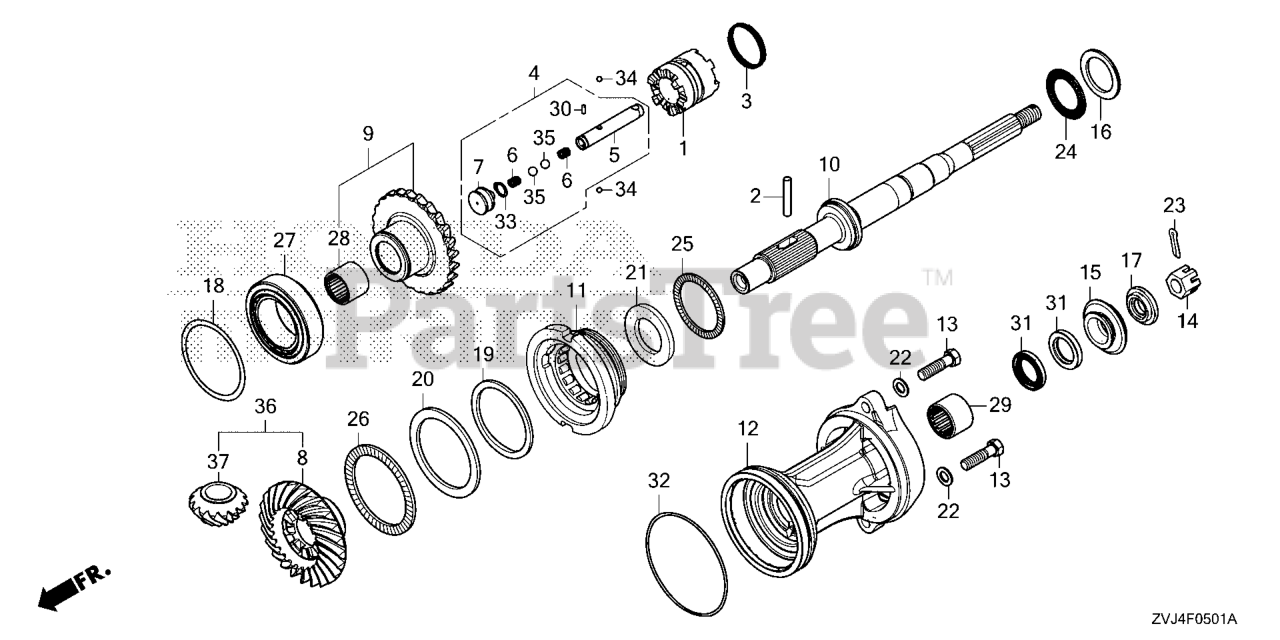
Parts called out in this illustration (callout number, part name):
1	SHIFTER, CLUTCH
2	PIN, SHIFTER (8X50)
3	RING, CROSS PIN
4	SLIDER, SHIFT
5	SLIDER, SHIFT
6	SPRING, SHIFT
7	PLATE, SHIFT
8	GEAR, BEVEL (24T) (FORWARD)(COUNTER ROTATION)
9	GEAR, BEVEL (24T) (REVERSE)(COUNTER ROTATION)
10	SHAFT, PROPELLER
11	HOLDER ASSY., BEARING (COUNTER ROTATION)
12	HOLDER, PROPELLER SHAFT *NH565* (GRAND PRIX WHITE)
12	HOLDER, PROPELLER SHAFT *NHB14M* (AQUA MARINE SILVER METALLIC)
12	HOLDER *NH565*
12	HOLDER *NHB14M*
13	BOLT, HEX. (12X45)
14	NUT, CASTLE (18MM)
15	WASHER, PROPELLER THRUST
16	WASHER, THRUST BEARING
17	WASHER, PROPELLER
18	SHIM A, BEVEL (0.10)
18	SHIM B, BEVEL (0.15)
18	SHIM C, BEVEL (0.30)
18	SHIM D, BEVEL (0.50)
19	SHIM A, BEVEL (0.10) (COUNTER ROTATION)
19	SHIM B, BEVEL (0.15) (COUNTER ROTATION)
19	SHIM C, BEVEL (0.30) (COUNTER ROTATION)
19	SHIM D, BEVEL (0.50) (COUNTER ROTATION)
20	WASHER, THRUST (85X110X2)
21	WASHER, THRUST (48X74X3) (COUNTER ROTATION)
22	WASHER, PLAIN (12MM)
23	PIN, SPLIT (4.0)
24	BEARING, THRUST (F)
25	BEARING, NEEDLE (50X72X4.5)
26	BEARING, THRUST NEEDLE (85X110X4)
27	BEARING, RADIAL BALL (55X100X21)
28	BEARING, NEEDLE (28X39X30)
29	BEARING, NEEDLE (32X42X30)
30	ROLLER (3X13.8)
31	SEAL, WATER (30X45X7)
32	O-RING (121X3.1)
33	CIRCLIP (OUTER) (15MM)
34	BALL, STEEL (#7) (7/32)
35	BALL, STEEL (#12) (3/8)
37	GEAR, PINION (COUNTER ROTATION)
